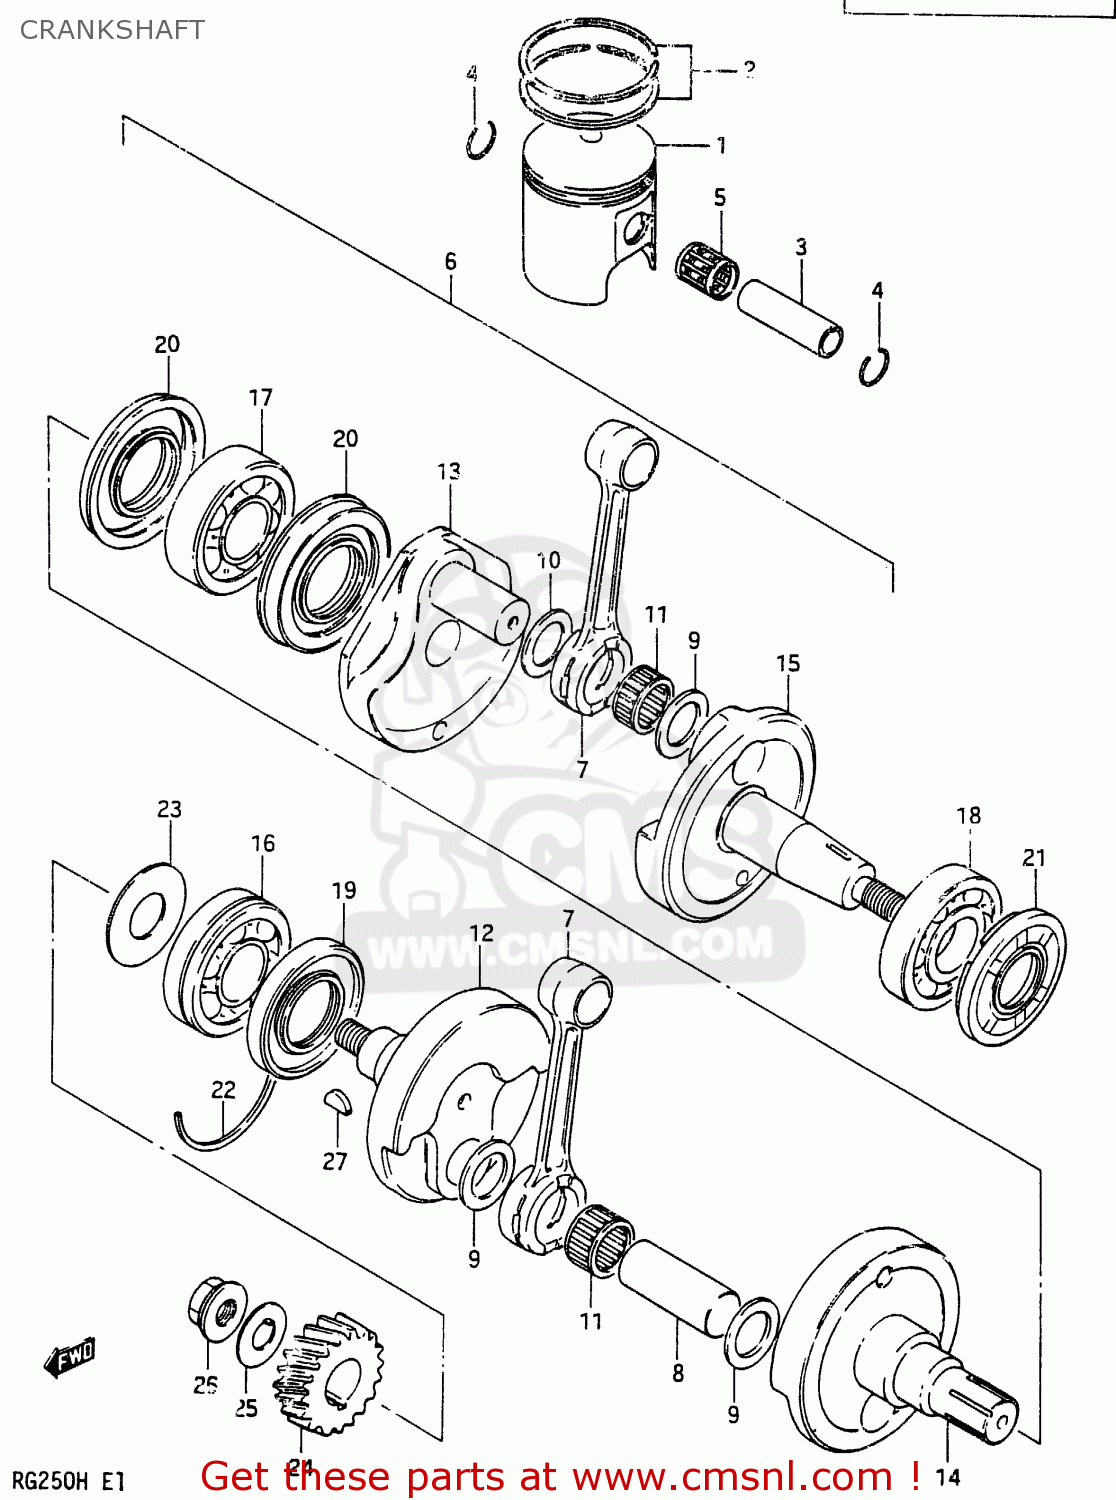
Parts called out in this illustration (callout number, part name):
1	PISTON
2	RING SET,PISTO
3	PIN,PISTON 14MM
4	RING,SNAP 14MM
5	BEARING 14X18X19.8
6	CRANKSHAFT ASSY
7	CONNECTING ROD
8	PIN, CRANK
9	WASHER(22X35X1)
10	WASHER
11	BEARING
12	CRANKSHAFT, RH
13	WEB, CRANK
14	CRANKSHAFT, MIDDLE
15	CRANKSHAFT, LH
16	BEARING(25X62X17)
17	BEARING
18	BEARING
19	SEAL,OIL(32X62X8)
20	SEAL,OIL(33.5X62X8)
21	SEAL,OIL(25X56X6)
22	C RING
23	WASHER(20X48X1)
24	GEAR, PRIMARY DRIVE (NT:24)
25	WASHER
26	NUT
27	KEY
